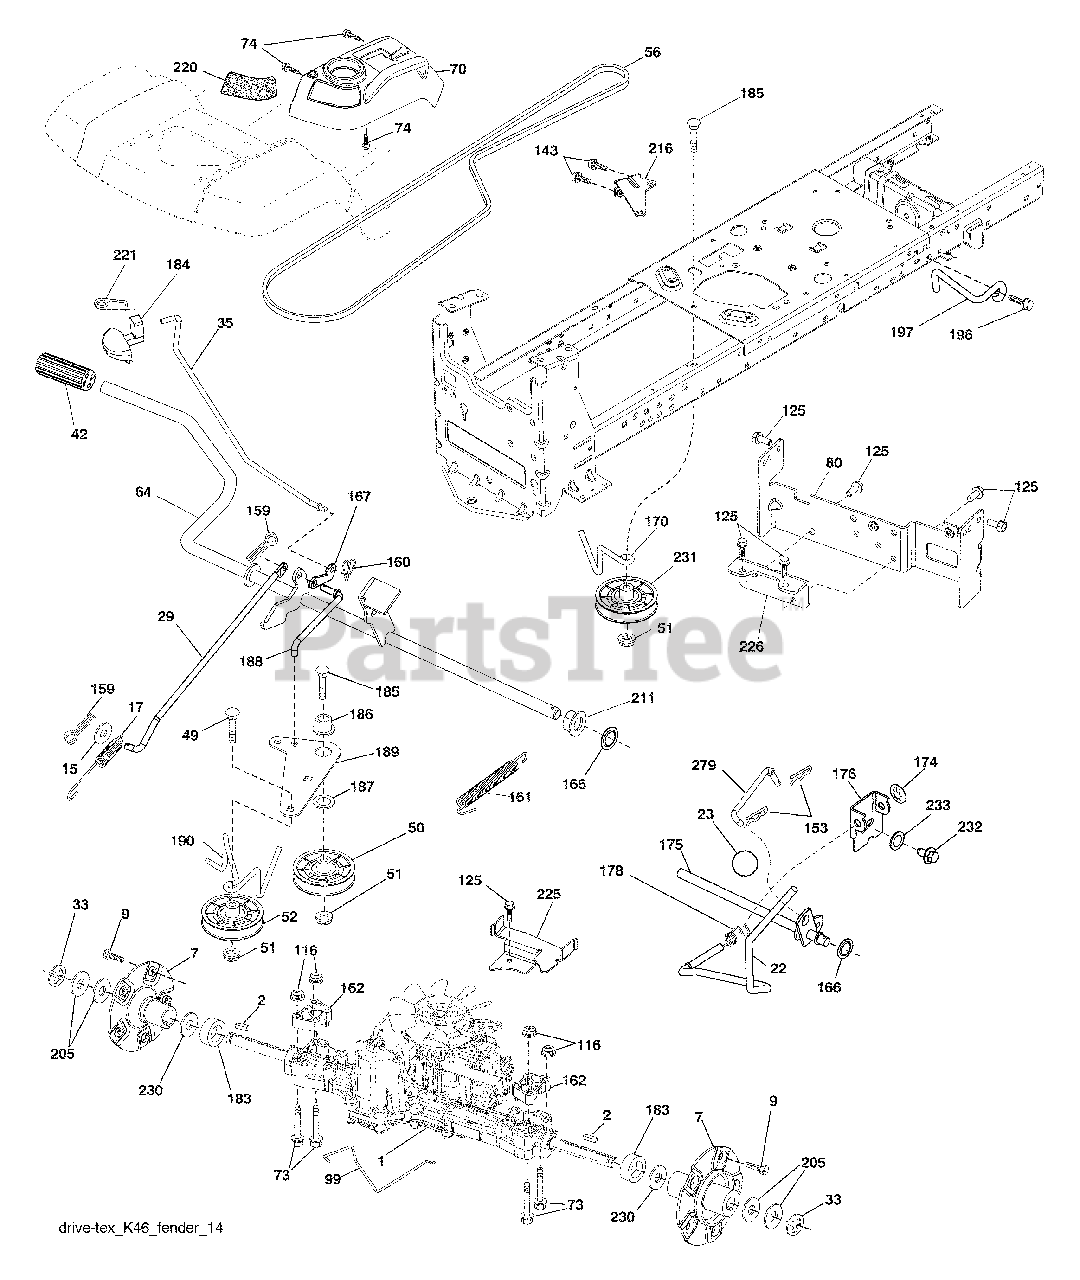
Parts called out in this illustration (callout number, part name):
1	Transaxle, TUFFTORQ K46 AW
7	Hub Asm. Wheel Rear 22" TX GT .06
9	Bolt Hub Wheel Rear
15	Washer 13/32 x 13/16 x 16 Ga.
17	Spring Brake
29	Rod, Brake
35	Rod Brake Park
42	Cover Foot Pedal
50	Pulley Idler Flat
51	Lock Nut 3/8-16
52	Idler V-Groove 910" Offset
56	V-Belt Drive
64	Shaft Asm. Pedal Brake Control
70	Console Asm.
73	Bolt Hex Flghd 5/16-18 x 3.75
74	Screw 1/4 x 1/2
80	Strap Torque
99	Rod Bypass
116	Nut Lock Hex Flange 5/16-18
125	Screw 5/16-18 x 3/4
143	Screw 5/16-18 x 1/2
153	Retainer Spring
159	Pin Cotter 1/8 x 3/4
160	Retainer Clip
161	Spring Return Clutch
162	Spacer Transaxle 18 and 22
166	Nut Push
167	Latch Brake Parking
170	Keeper Belt Centerspan
175	Shaft Asm Shift
176	Arm Clevis Rod Shift
178	Spring Shift
183	Spacer Split
184	Handle Parking Brake
185	Bolt Rdhd Sqnk 3/8-16 x 2-3/4 Gr. 5
186	Spacer Retainer
187	Washer
188	Link Clutch Ground Drive
189	Bellcrank Ground Drive
190	Keeper Bellcrank Ground Drive
196	Screw 3/8-16 x 1
197	Link Clutch Anti-Rotation
211	Bushing Brake Shaft
216	Bracket Pulley Idler
220	Reflector RH
221	Retainer Spring Clip Handle
225	Keeper Belt Trans.
226	Bracket Mount Torque
230	Washer Hardened
231	Idler V-Groove 1.688" Offset
232	Bolt 7/16-14 x 1 Gr. 5
233	Washer Serrated
279	Link Shift
